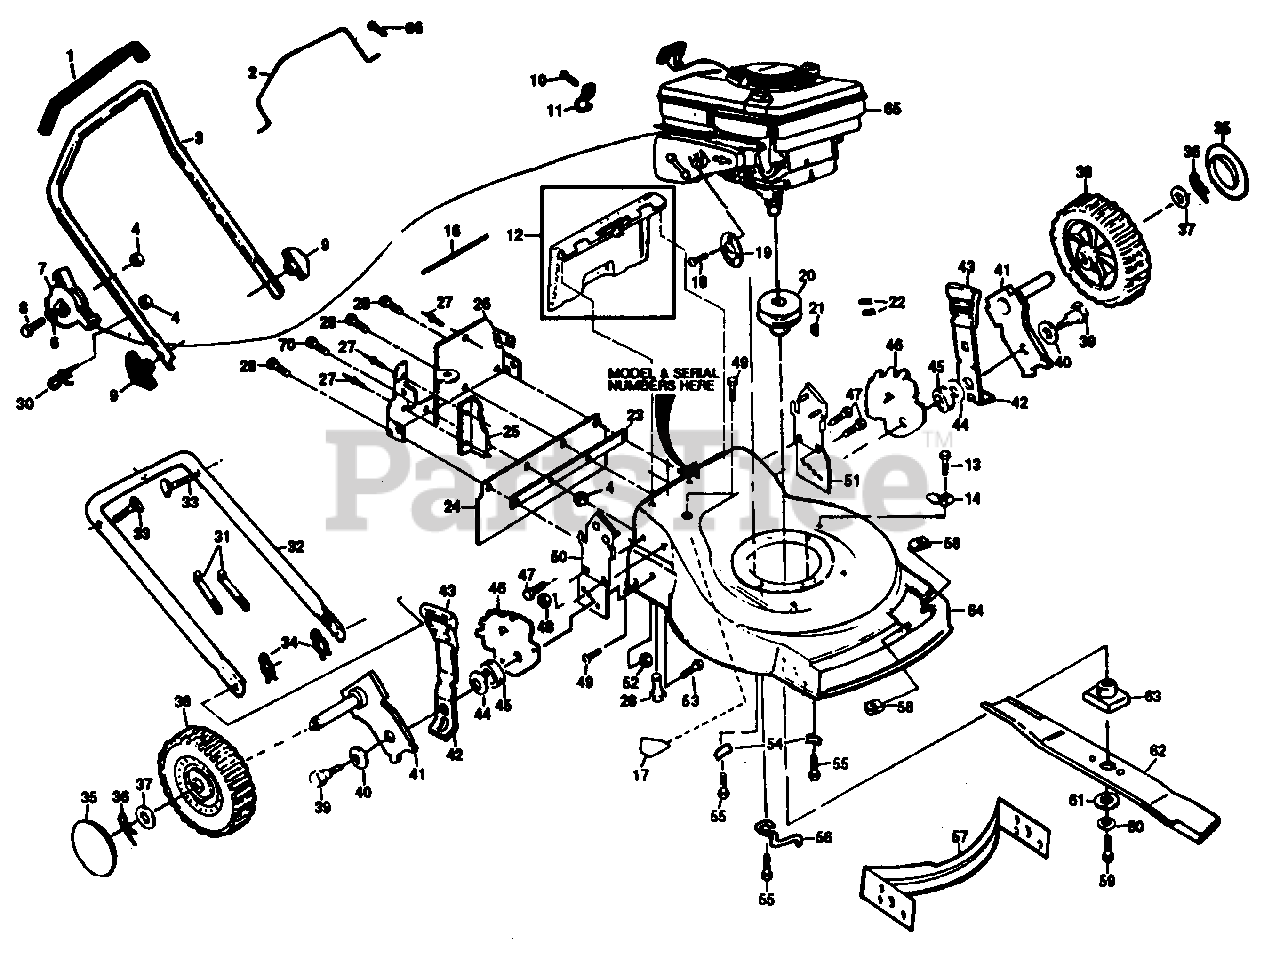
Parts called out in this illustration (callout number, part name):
1	Handle Grip (AYP part number)
2	Control Bar (AYP part number)
3	Upper Handle (AYP part number)
4	Locknut (AYP part number)
6	Washer (AYP part number)
7	Throttle Control
8	Machine Screw 1/4-20 x 2-3/4
9	Handle Knob (AYP part number)
10	Screw #10 x 5/8 (AYP part number)
11	Cable Clamp (Engine) (AYP part number)
12	Rear Door Kit (AYP part number)
13	Hex Washer Head Screw #10-24 x 1/2 (AYP part number)
14	Housing Cable Guide (AYP part number)
16	Hinge Rod (AYP part number)
17	Danger Decal (AYP part number)
18	Screw #8-32 x 3/8 (AYP part number)
19	Muffler Deflector
20	Engine Pulley (AYP part number)
21	Hi Pro Key #505 (AYP part number)
22	Set Screw 1/4-20 x 5/16 (AYP part number)
23	Backing Strip (AYP part number)
24	Rear Skirt (AYP part number)
25	Side Baffle (AYP part number)
26	Back Plate (AYP part number)
27	Pop Rivet (AYP part number)
28	Hex Head Tapping Screw 1/4-20 x 1/2 (AYP part number)
30	Rope Guide (AYP part number)
31	Tie Wire (AYP part number)
32	Lower Handle (AYP part number)
33	Handle Bolt
34	Hairpin Cotter (AYP part number)
35	Hubcap (AYP part number)
36	Retainer Clip (AYP part number)
37	Washer (AYP part number)
38	Wheel & Tire Assembly 9.00 x 2.00 (AYP part number)
39	Shoulder Bolt (AYP part number)
40	Belleville Washer (AYP part number)
41	Axle Arm (AYP part number)
42	Selector Spring (AYP part number)
43	Selector Knob (AYP part number)
44	Washer (AYP part number)
45	Spacer (AYP part number)
46	Wheel Adjusting Bracket (AYP part number)
47	Self-tapping Screw 5/16-18 x 3/4 (AYP part number)
48	Locknut 5/16-18 (AYP part number)
49	Hex Tapping Screw 1/4-20 x 1/2 (AYP part number)
50	Handle Bracket (Right) (AYP part number)
51	Handle Bracket (Left) (AYP part number)
52	Locknut 3/8-16 (AYP part number)
53	Carriage Bolt 5/16-18 x 5/8 (AYP part number)
54	Engine Washer (AYP part number)
55	Hex Head Thread Roling Screw 3/8-16 x 1 (AYP part number)
56	Belt Snubber (AYP part number)
57	Front Baffle (AYP part number)
58	Speed Nut (U Type) (AYP part number)
59	Hex Head Machine Screw 3/8-24 x 1-3/8 Gr. 8
60	Helical Lock Washer (AYP part number)
61	Hardened Washer (AYP part number)
62	Blade 22"
63	Blade Adapter
64	Lawn Mower Housing Kit (Inc. 17)
66	Screw #10-24 x .625 (AYP part number)
70	Screw, Hex, Head Machine 1/4-20 (AYP part number)
